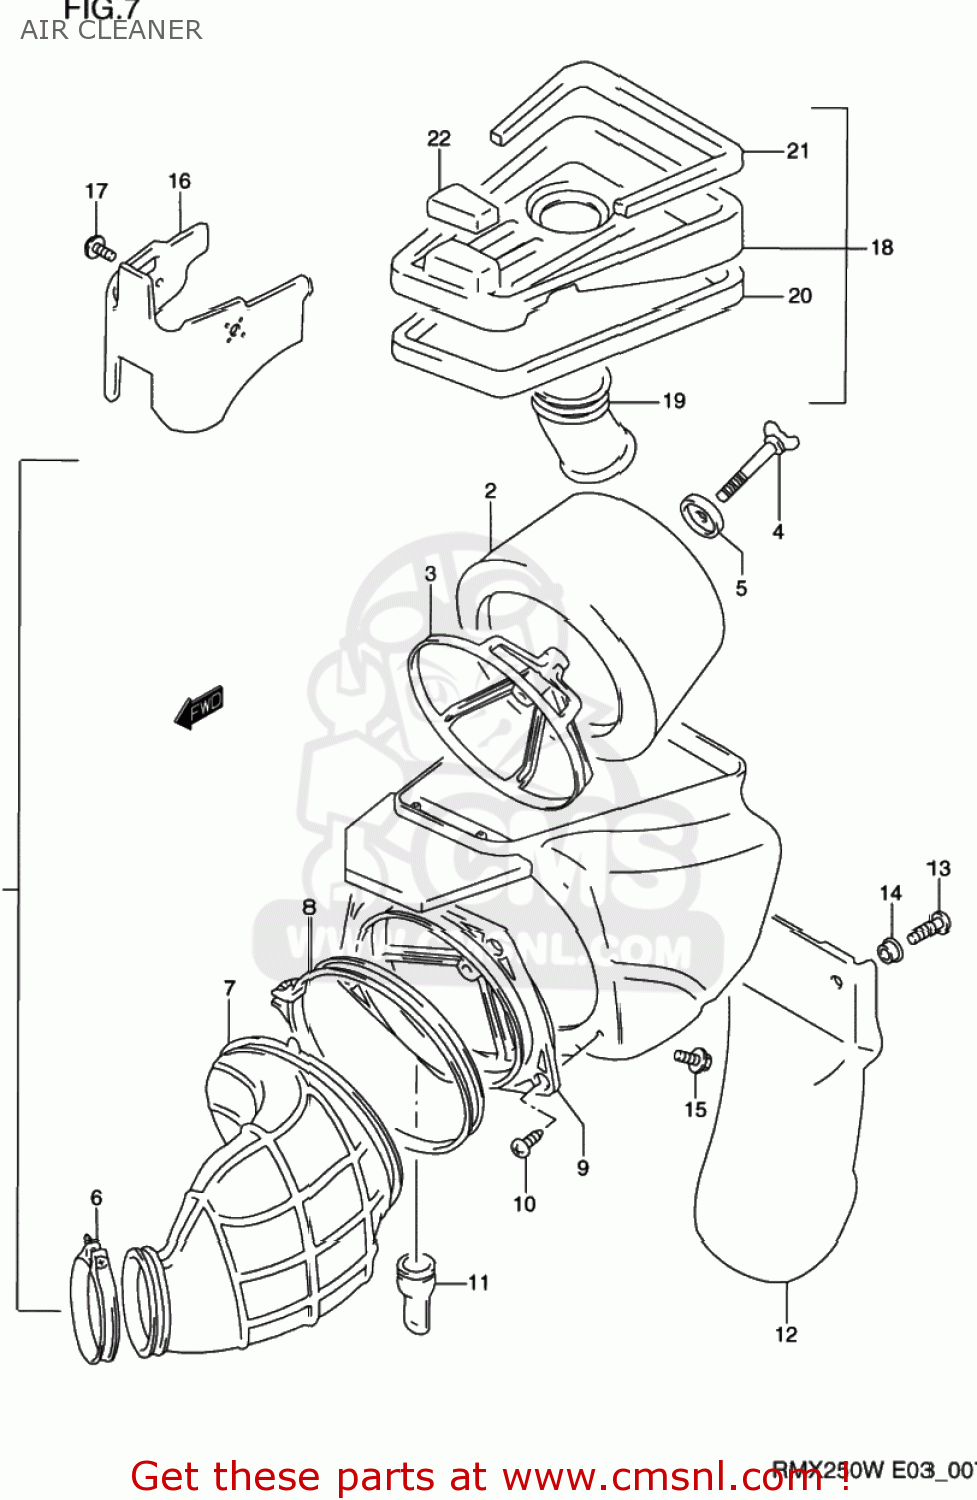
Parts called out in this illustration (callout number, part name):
1	CLEANER ASSEMBLY,AIR
2	FILTER
3	HOLDER,FILTER
4	BOLT,WING
5	WASHER,AIR CLEANER
6	CLAMP
7	TUBE,OUTLET
8	CLAMP
9	BASE,FILTER
10	SCREW
11	CAP,DRAIN
12	GUARD,MUD
13	SCREW
14	COLLAR
15	BOLT
16	GUARD,MUD
17	SCREW(6X12)
18	CAP,AIR CLEANER
19	TUBE,INLET
20	GASKET,CAP (NAS)
21	CUSHION
22	CUSHION
